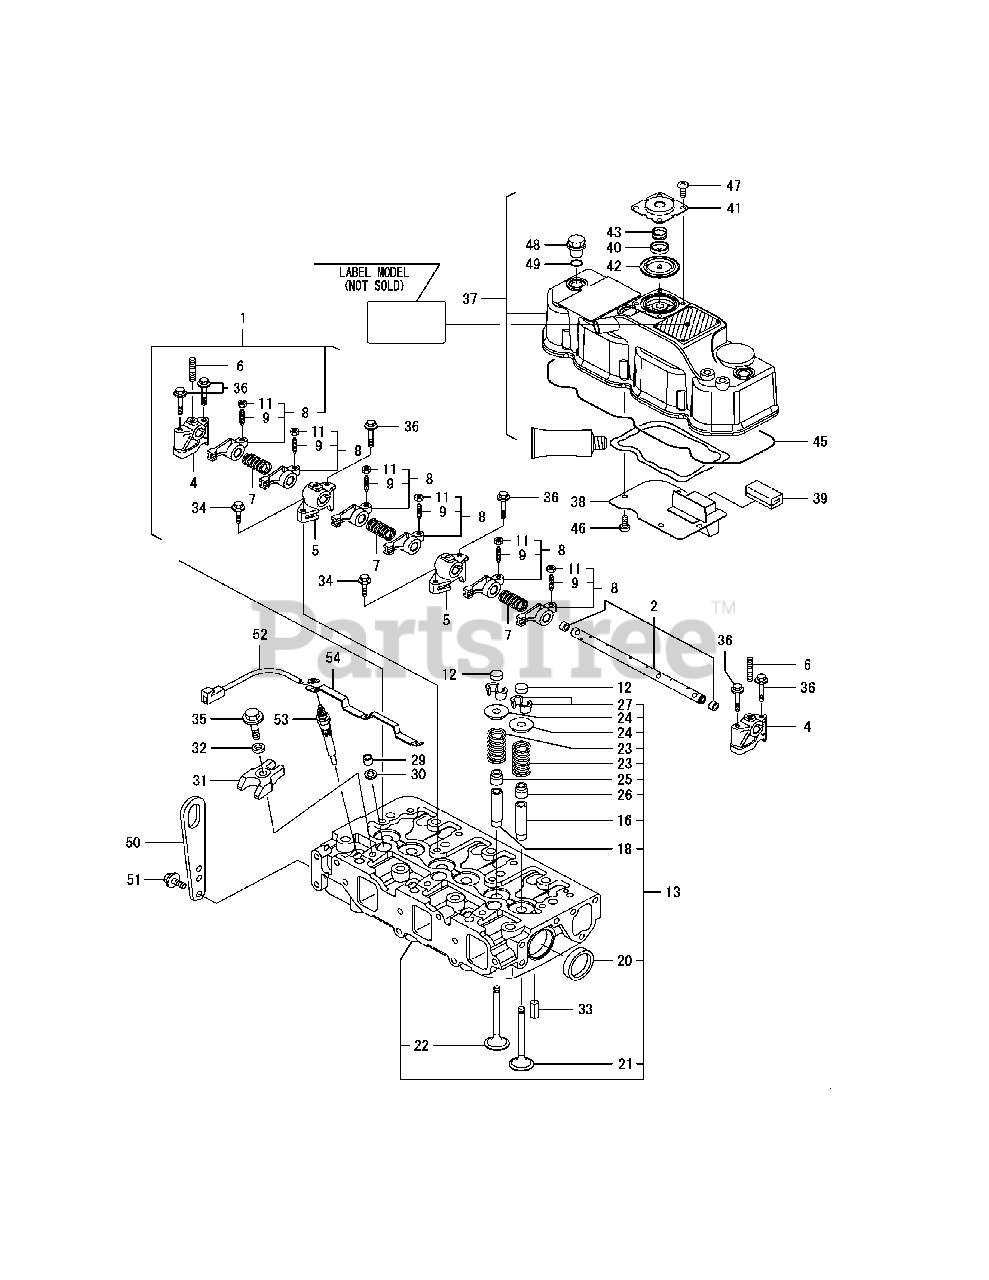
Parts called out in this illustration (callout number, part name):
1	SHAFT ASSY, ROCKER
2	SHAFT, ROCKER ARM
4	SUPPORT, ROCKER ARM
5	SUPPORT, ROCKER ARM
6	STUD, 8X18
8	ARM ASSY, ROCKER
13	HEAD ASSY, CYLINDER
22	VALVE, EXHAUST
24	RETAINER, SPRING
25	SEAL, VALVE STEM
26	SEAL, VALVE STEM
29	PROTECTOR, NOZZLE
31	RETAINER, NOZZLE
33	SPRING PIN 6X12
34	BOLT M 8X 25 PLATED
35	BOLT M 8X 35 PLATED
36	BOLT M 8X 50 PLATED
37	COVER ASSY, VALVE
39	BAFFLE, BREATHER
40	PLATE, DIAPHRAGM
41	COVER, DIAPHRAGM
43	SPRING, DIAPHRAGM
45	GASKET, VALVE COVER
46	SCREW 5X10,TAPPING
47	SCREW 5X10,TAPPING
49	O-RING 1A P 12.0
50	LIFTER, ENGINE
51	BOLT M 8X 16 PLATED
52	HARNESS, GLOW PLUG
54	CONNECTOR, GLOW PLUG
